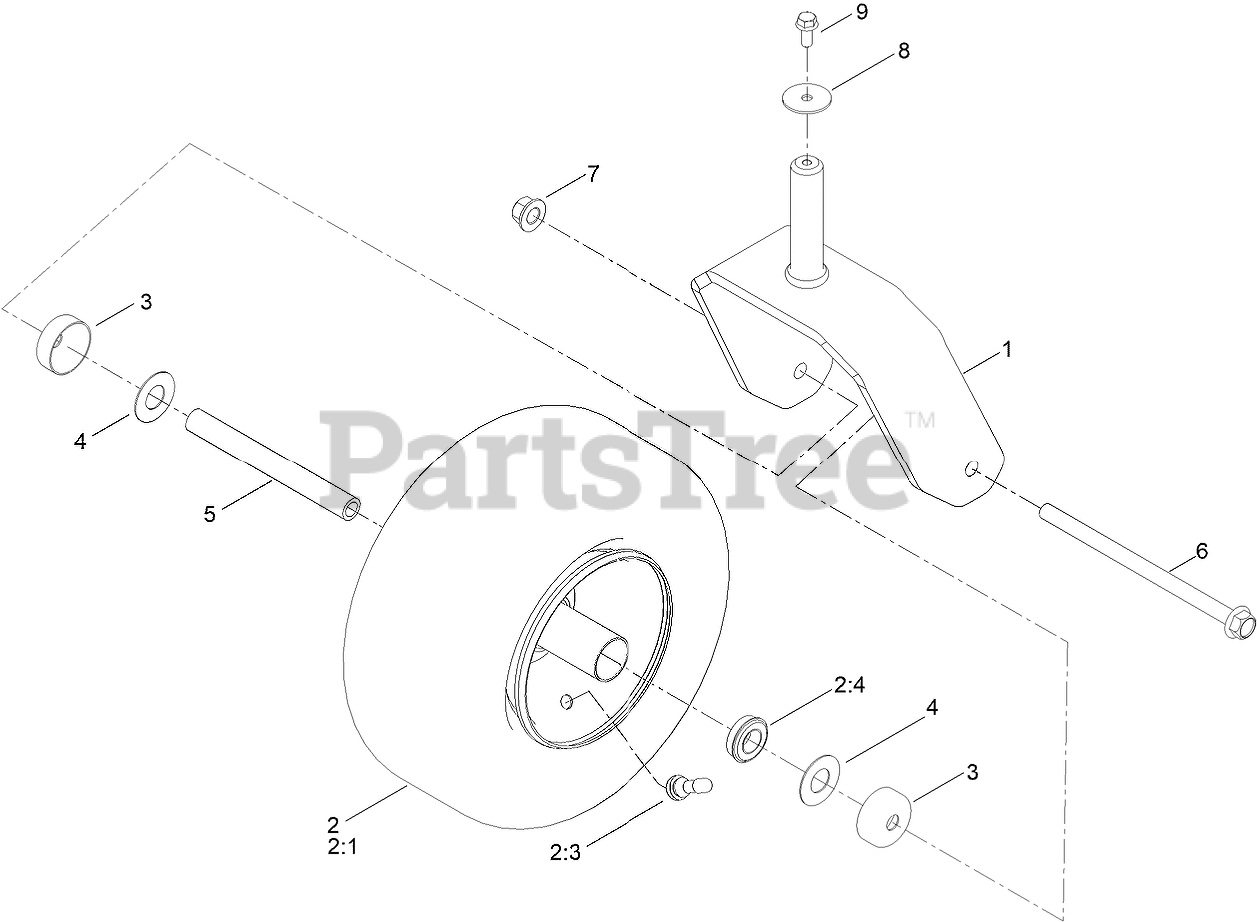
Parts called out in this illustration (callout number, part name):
1	FORK ASM
2	TIRE ASM
2:4	BEARING
3	GUARD-SEAL
4	WASHER
5	SPANNER-WHEEL
6	SCREW-HHF
7	NUT-LOCK
8	WASHER-FLAT
9	SCREW-HHF
